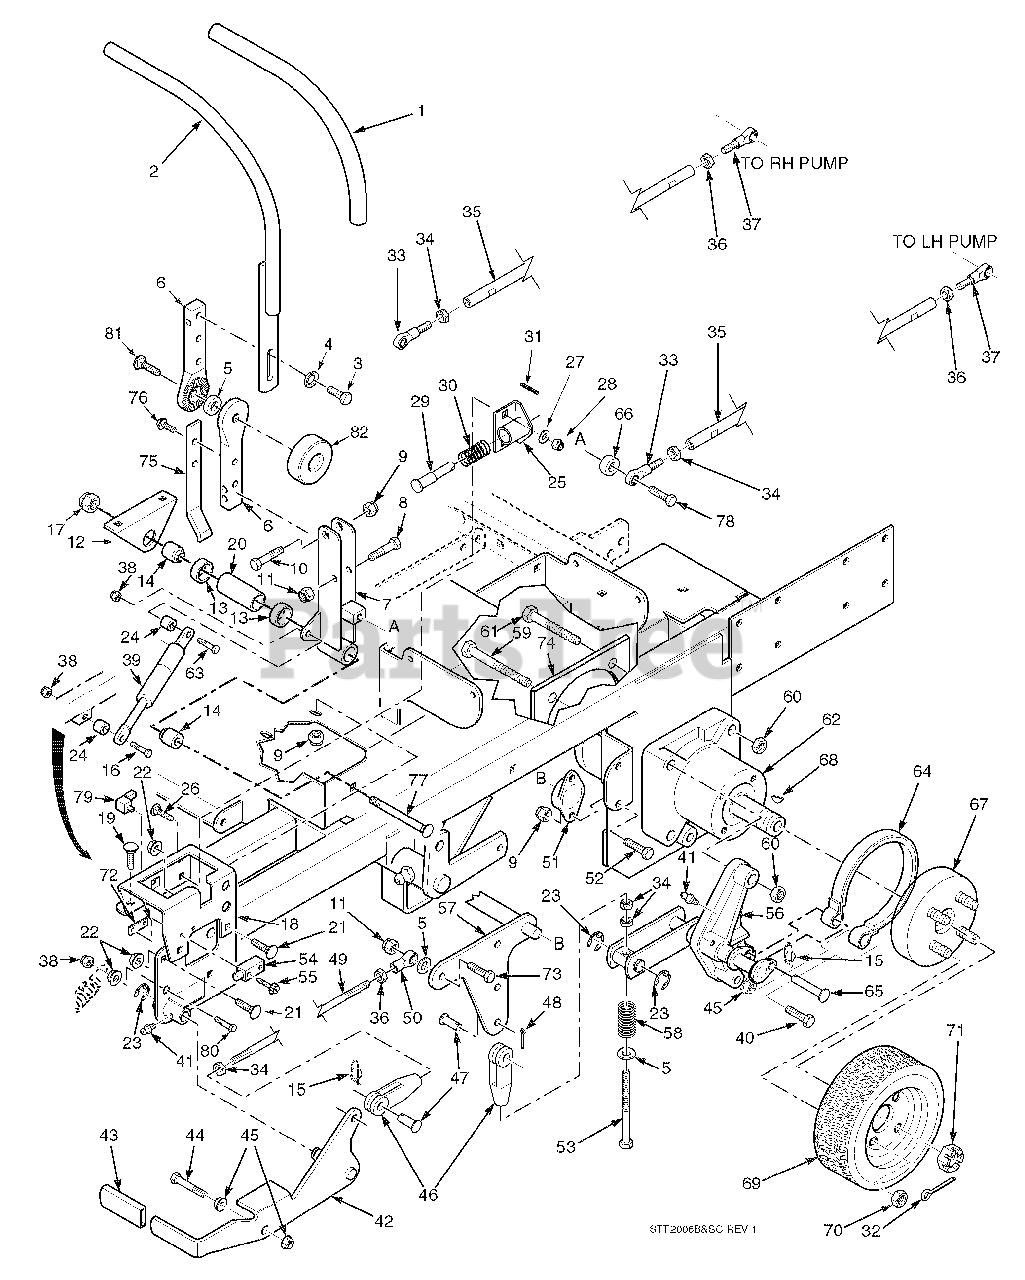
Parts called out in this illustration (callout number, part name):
1	Grip, Handle Bar
2	Handle Bar, LH
3	Bolt, Hex Head 5/16-18 x 1"
4	Lockwasher, 5/16"
5	Rubber Spacer
6	Bar, Control Lever
7	Control Lever Weldment, LH
8	Bolt, Hex Head 5/16-18 x 2"
9	Nut, Hex Elastic Stop 5/16-18
10	Bolt, Hex Head 3/8-16 x 2"
11	Nut, Hex Elastic Stop
12	Mount, Control Linkage
13	Ball Bearings, Neutral Return
14	Spacer
15	Pin, Rue Cotter 3/8 Dia.
16	Bolt, Hex Head, 5/16-18 x 2.75 Zinc
17	Nut, Hex Elastic Stop 5/8-11
18	Bracket, Control Lever LH
19	Bolt, Carriage 5/16-18 x 1"
20	Spacer, Bearing
21	Bolt, Carriage 5/16-18 x 3/4"
22	Nut, Hex Serrated Flange 5/16-18
23	Ring, Retaining 5/8" External "E"
24	Spacer
25	Bracket, Neutral Return
26	Bolt, Carriage 1/4-20 x 3/4"
27	Flatwasher, 1/4"
28	Nut, Hex Elastic Stop 1/4-20
29	Pin, Retaining Spring
30	Spring
31	Roll Pin, Spring 5/32 x 3/4"
32	Pin, Cotter 9/16 x 1-1/2"
33	Rod End, Male 3/8-24 RH Thread
34	Nut, 3/8-24 RH Thread
35	Tube, Control Link Air-Cooled Engine
36	Nut, Hex 3/8-24 LH Thread
37	Rod End, Male 3/8-24 LH Thread
38	Locknut, 5/16-18, Elastic Stop
39	Gas Damper
40	Bolt, Hex Head 1/2-13 x 2-1/2" Grade 8
41	Grease Fitting
42	Lever, Parking Brake
43	Grip, Parking Brake
44	Bolt, Hex Head 3/8-16 x 2-3/4"
45	Nut, Hex Serrated Flange 1/2-13
46	Clevis, Traction Control
47	Pin, Clevis 3/8-16 x 1-1/16"
48	Pin, Cotter 3/32 x .75
49	Rod, Parking Brake
50	Rod End, LH Thread
51	Bushing, Self Align
52	Bolt, Hex Head 5/16-18 x 3/4"
53	Bolt, Hex Hd 3/8-24 x 5-1/4", 23/4" Thrd
54	Switch
55	Screw, Hex SLTD WSHR Head #10 32 x 3/4"
56	Brake Linkage, LH
57	Bellcrank, Brake Actuator
58	Spring
59	Bolt, Hex Head 1/2-13 x 3-3/4"
60	Locknut, Hex 1/2-13 Center Lock
61	Bolt, Hex Head 1/2-13 x 2-1/2"
62	Wheel Motor, Hydro-Gear 15E
62	Wheel Motor, Ross
62	Wheel Motor, Hydro-Gear 18E
63	Bolt, Hex Head, 5/16-18 x 1.75, Zinc
64	Brake Band Assembly
65	Pin, Clevis 3/8" Dia. x 1.93"
66	Spacer
67	Wheel Hub/Brake Drum Assembly
68	Key, Woodruff 5/16 x 1"
69	Wheel Assembly 23 x 10.5-12
69	Rim W/Valve Stem
69	Tire, 23 x 10.5-12
69	Wheel Assembly 24 x 12-12 Turf Master
69	Tire, 24 x 12-12 Turf Master
70	Lug Nut, 1/2-20
71	Nut, Hex Castle
72	Threaded Plate
73	Bolt, Hex Head 3/8-16 x 1-1/2"
74	Plate Weldment, Motor Backing
75	Actuator Switch
76	Bolt, Hex Serrated Flange 5/16-18 x 3/4"
77	Bolt, Carriage 3/8-16 x 4-3/4"
78	Bolt, Hex Head 3/8-16 x 1"
79	Switch
80	Bolt, Hex Head 3/8-16 x 1-1/4" Grade 8
81	Bolt, Carriage 5/16-18 x 1-1/2"
